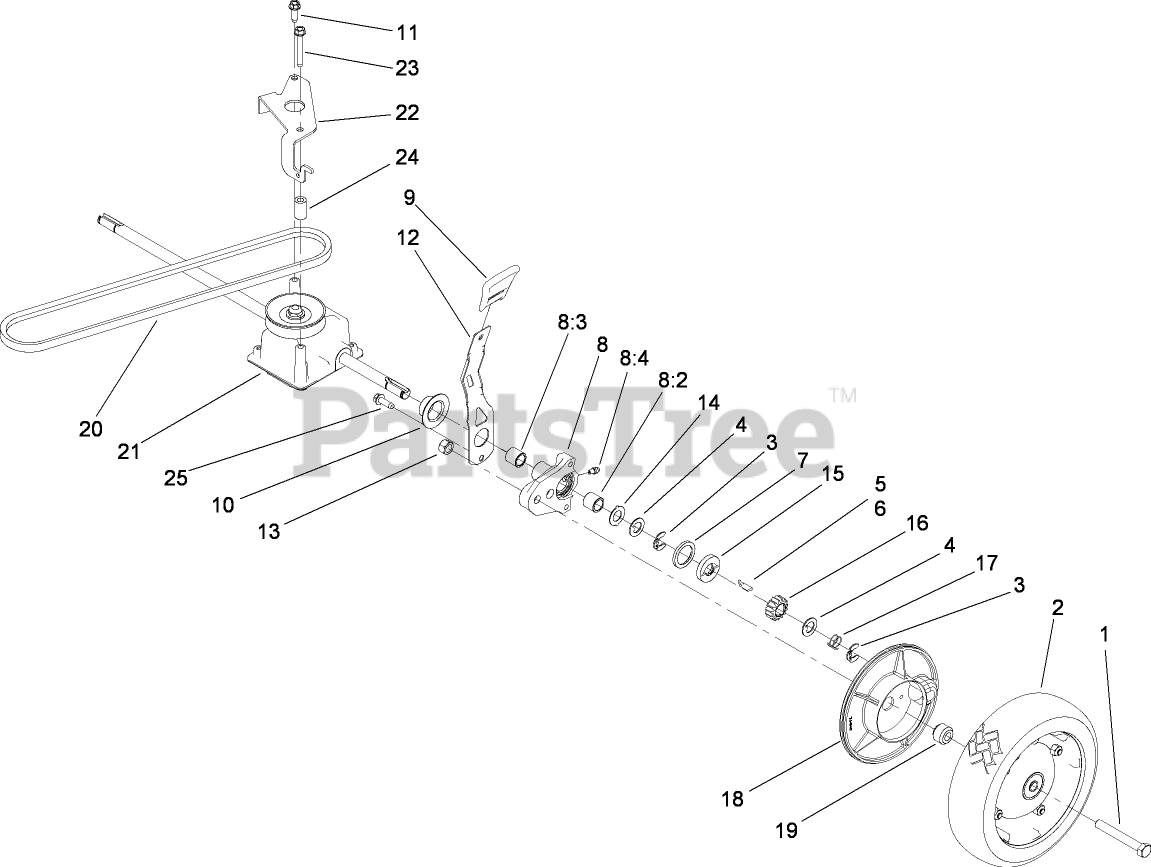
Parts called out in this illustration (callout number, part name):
1	SCREW-HH
3	RING-RETAINING,CLIP
4	WASHER-THRUST, KEYED
5	KEY-ROCKING, RH
6	KEY-ROCKING, LH
7	RING-FRICTION
8	PIVOT ARM ASM
8:2	BUSHING
8:3	BUSHING
8:4	FITTING-GREASE
9	KNOB-HOC
10	CAP-END
11	SCREW-HWHTF
12	ARM-SPRING
13	LOCKNUT
14	WASHER-ARM, PIVOT
15	WASHER-CLUTCH
16	GEAR-PINION
17	SPRING-COMPRESSION
18	COVER-WHEEL
19	SPACER-COVER, WHEEL
20	V-BELT
21	GEAR CASE ASM
22	BRACKET-GEARBOX
23	SCREW-HWHTF
24	BUSHING-PLATE, ACTUATOR
25	SCREW-HWH
